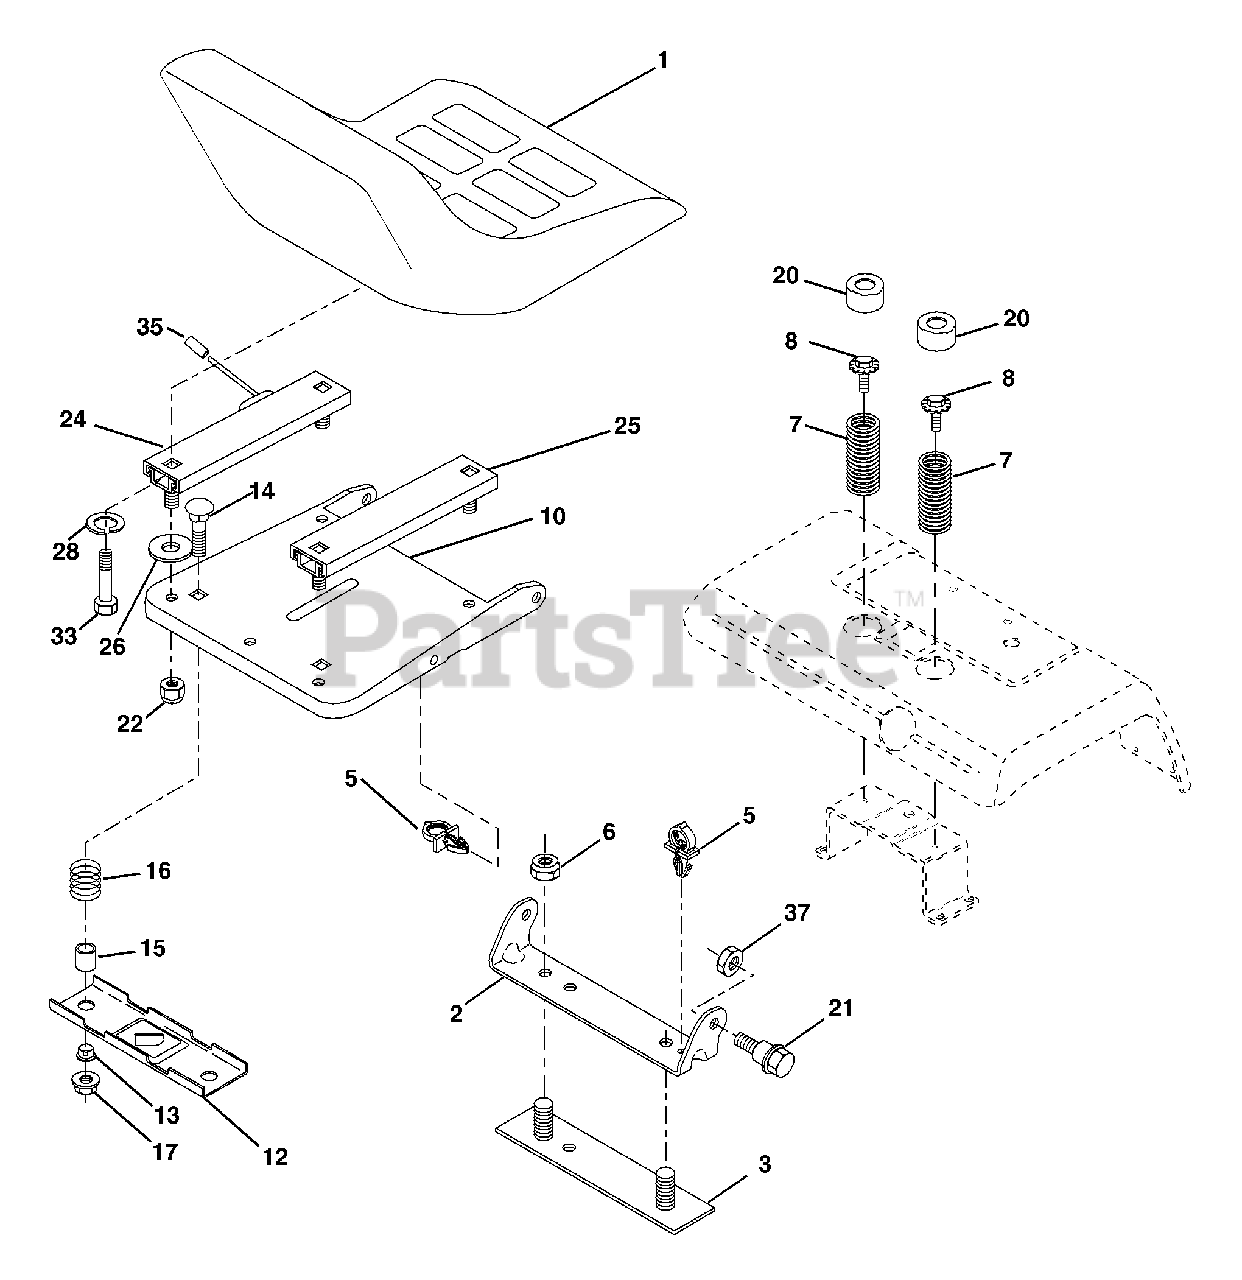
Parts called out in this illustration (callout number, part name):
1	Seat
2	Bracket, Pivot Seat
3	Strap Asm Fender
5	Clip, Push In Hinged
6	Nut, Crownlock 3/8-16
7	Spring, Seat Cprsn
8	Bolt 5/16-18 Unc x 3/4
10	Pan, Seat
12	Bracket, Mounting Switch
13	Bushing, Snap
14	Bolt, Carriage 1/4-20 x 1-1/2
15	Spacer, Split
16	Spring, Cprsn
17	Nut, Lock 1/4 Lge Flg Gr. 5
20	Cap, Spring Seat
21	Bolt, Shoulder 5/16-18
22	Nut Crownlock 5/16-18
24	Track Slide Seat LH Locking
25	Track Slide Seat RH Free
26	Washer 11/32 x 5/8 x 12 Ga.
28	Washer Split
33	Bolt Fin Hex 5/16-18 x 1
35	Cap Vinyl
37	Nut, Crownlock 5/16-18
